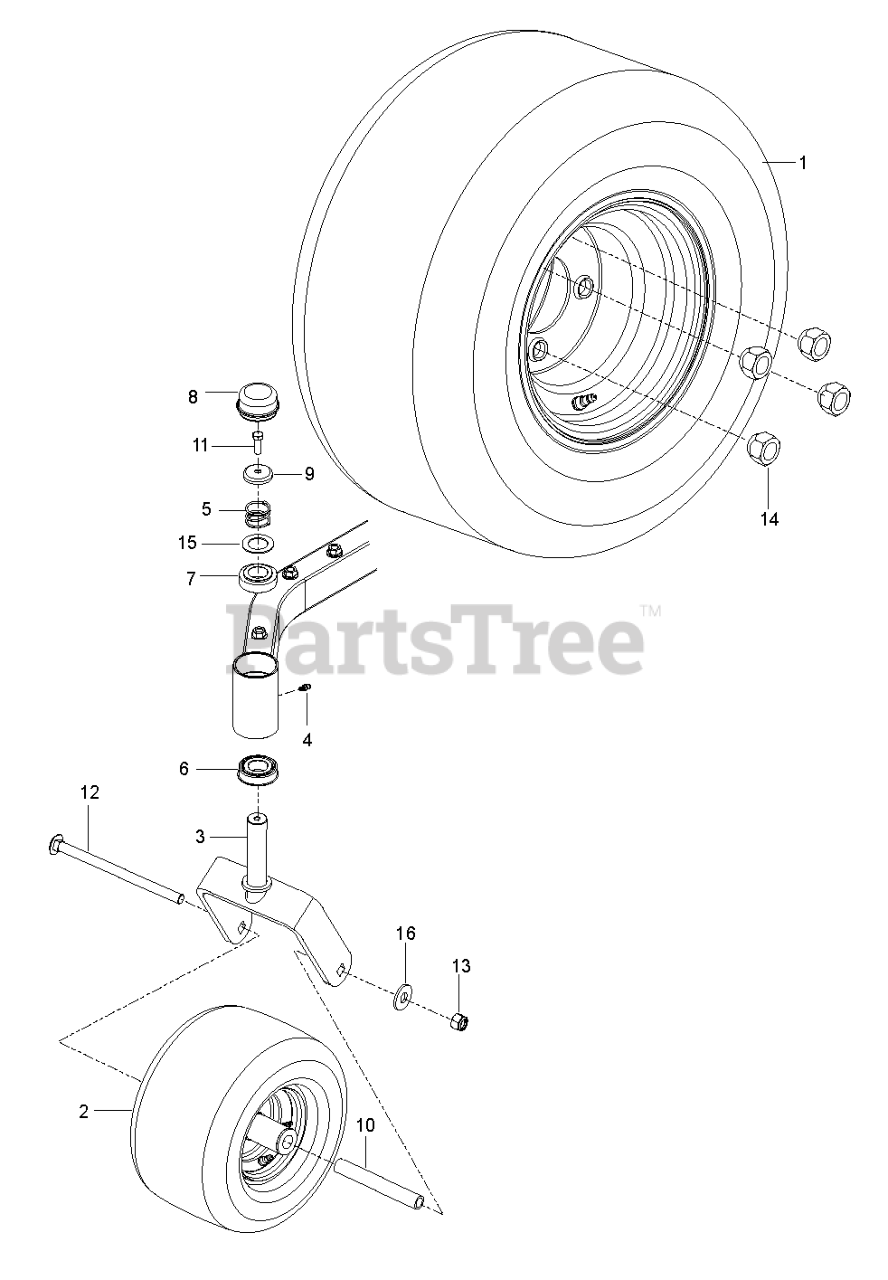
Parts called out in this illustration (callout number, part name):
1	WHEEL CARLSTAR 18X8.5-8" YELLO
2	WHEEL ASSY ASM.WHEEL.11X6-5 SM
4	ZERK, 3/16, DRIVE IN
5	SPRING, CASTER
6	BEARING FLANGED
7	BUSHING, CASTER
8	GREASE CAP
9	CASTER.PLUG
10	SPACER.PIVOT
11	5/16-18X1 HHB G5W/NY
12	RHSNB 1/2-13 X 7.5
13	NUT. 1/2-13 HEX CNTRLK GR 5 ZD
14	NUT.1/2-20.UNF-2B.GR.8.YL
15	WASHER, 1.025 ID X 1.64
16	WASHER.9/16 X 1 3/8 X 12 GA.
